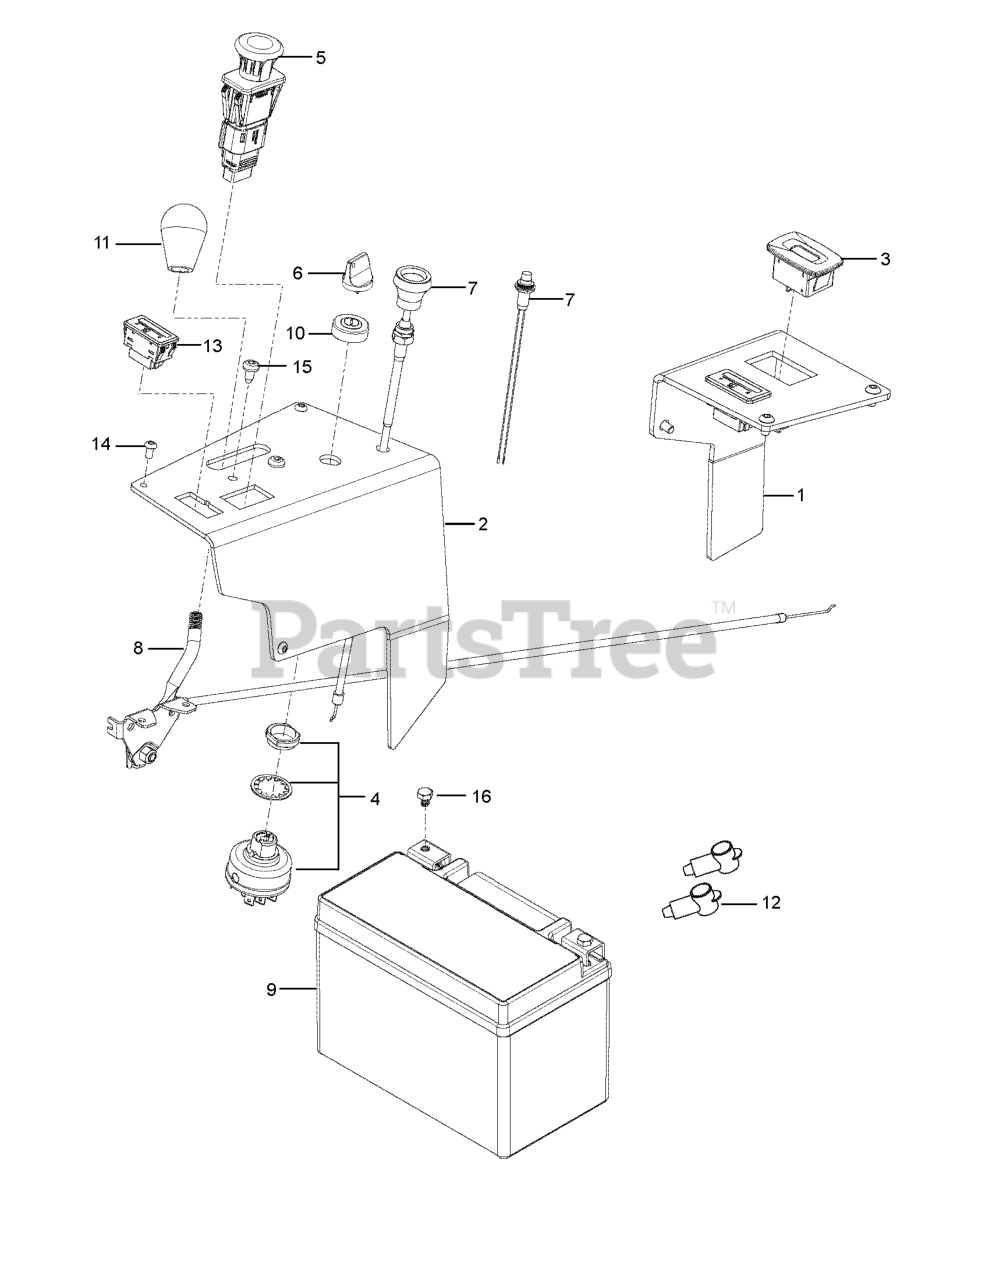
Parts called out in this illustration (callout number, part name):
1	PANEL.LH.CONTROL.PNT.X498
2	PANEL.RH.CONTROL.PNT.X498
3	GUAGE.SRVCMNDR.HRMTR.
4	SWITCH, IGNITION, INDAK
5	SWITCH.PTO.10AMP.SEALED.6P.SPS
6	KEY, IGNITION
7	CABLE, CHOKE, 48"
7	LED.LIGHT.SERVICE.EFI
8	THROTTLE.CONTROL.POST.MZ/PZ.46
9	Brackets
9	BATTERY.STARTER.AGM.LEOCH.8AH
9	Batteries
10	CAP IGNITION NUT
11	KNOB - SHIFT
13	FUEL.GAUGE.LED.LEVEL.Z500
14	SCR #10-24 X 3/8 SKT HD BLK OX
15	SCREW T-30 1/4-20 X
16	SCREW M6 X 8MM HEX CAP
